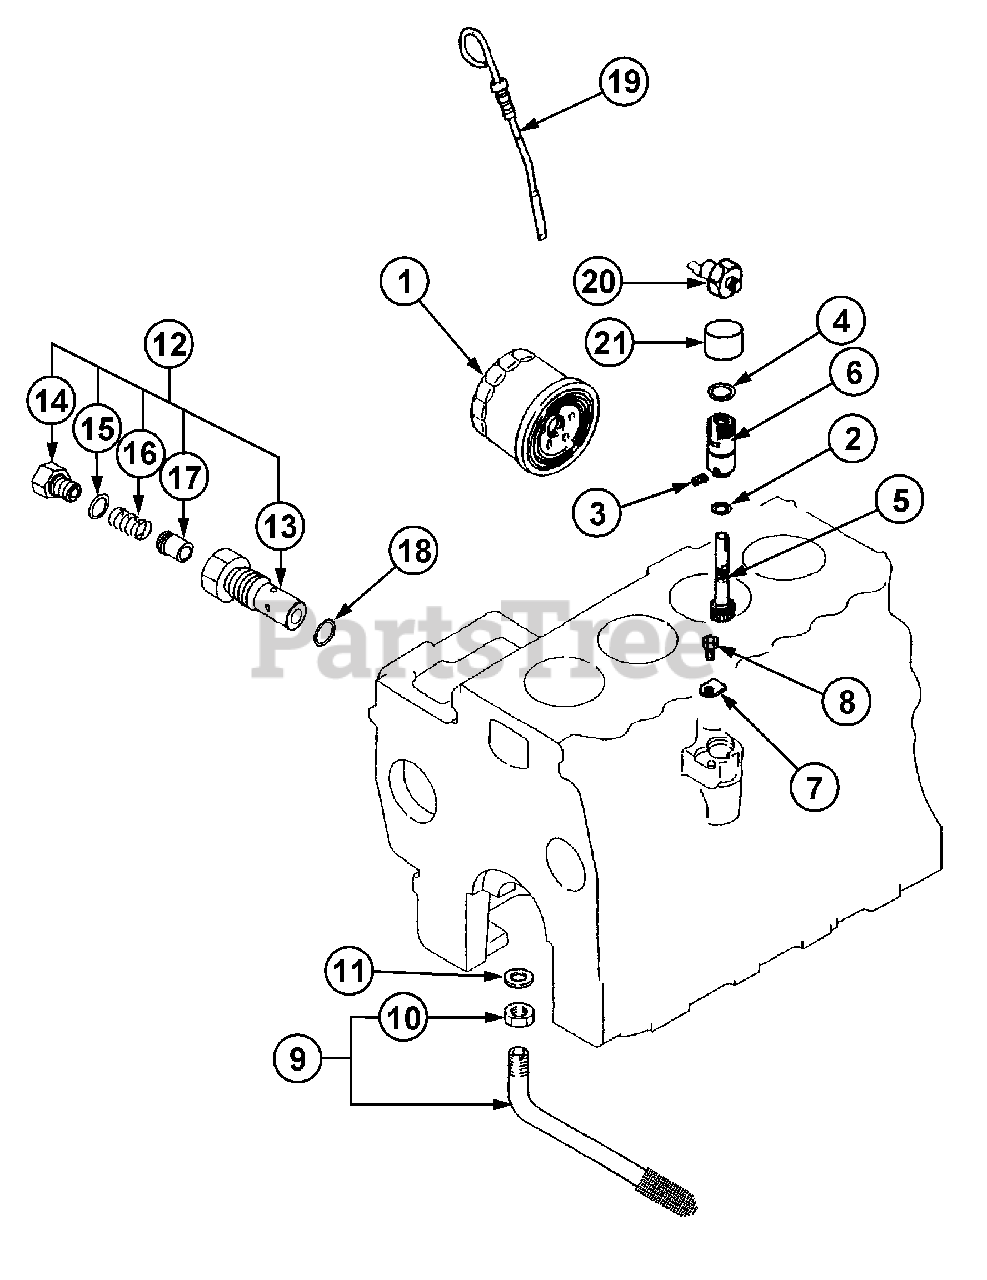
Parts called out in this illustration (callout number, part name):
1	Filter Assy, Oil
3	Pin, Spring
4	O-Ring
5	Gear
8	Bolt, w/Washer
9	Strainer Assy
12	Valve Assy, Relief
13	Housing, Valve
14	Plug
15	Gasket
16	Spring, Relief
17	Plunger, Relief
19	Gear, Oil Level
20	Switch, Oil Press
21	Plug, Shipping
